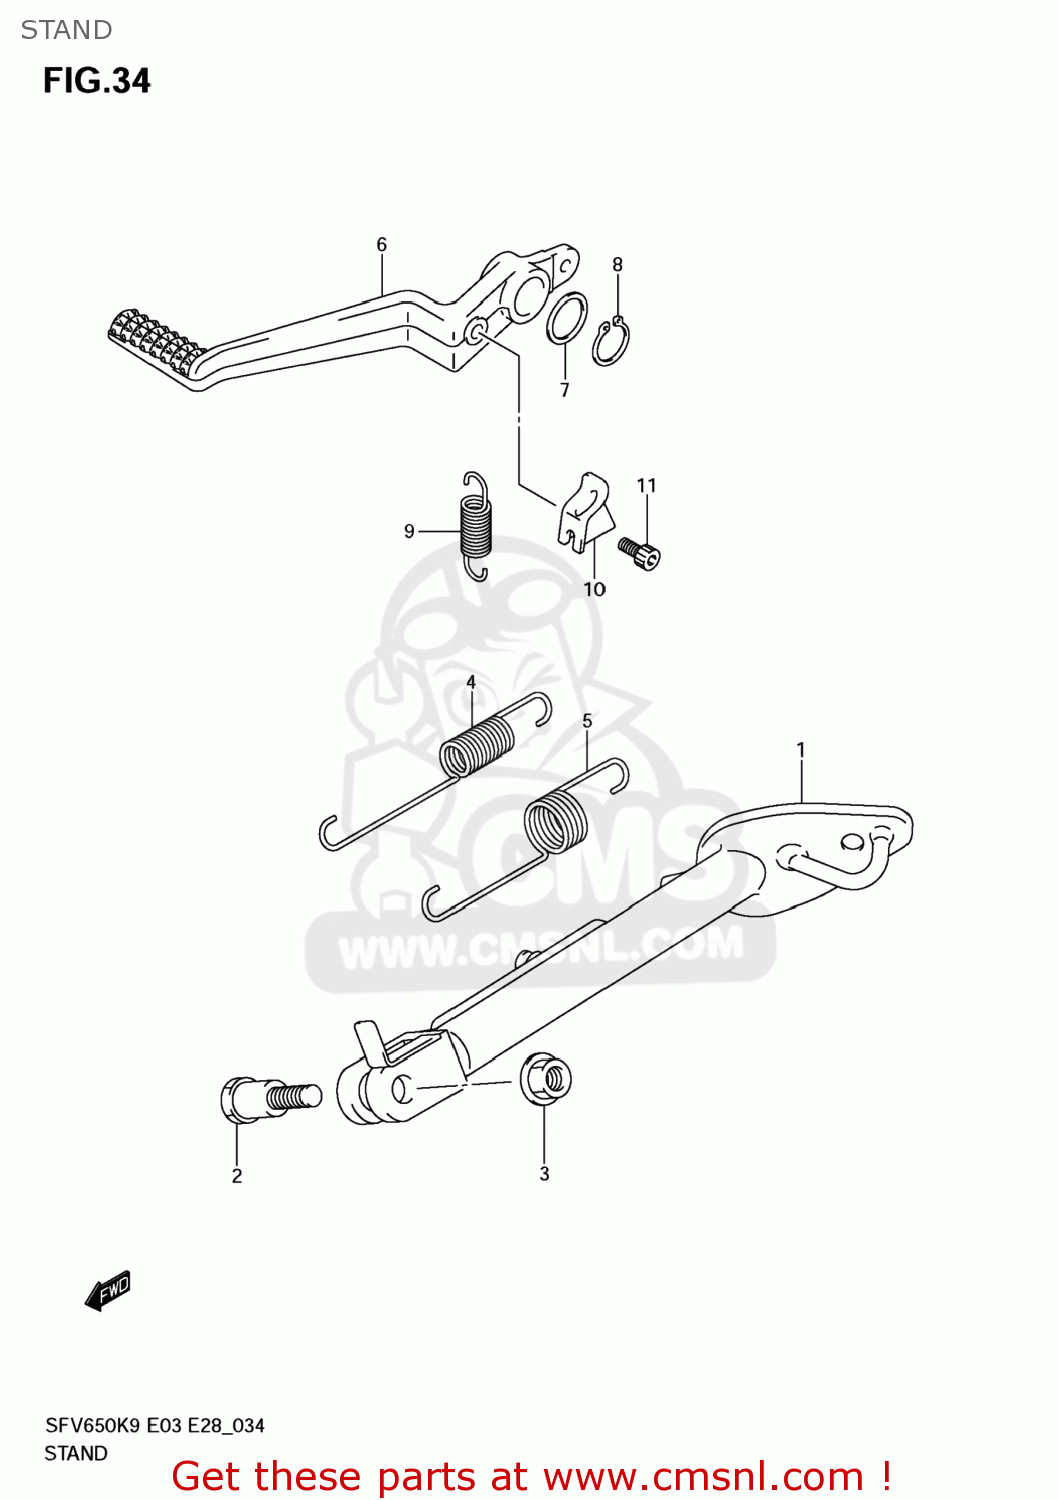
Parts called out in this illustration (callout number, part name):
1	STAND,PROP
2	BOLT(10X21)
3	NUT
4	SPRING
5	SPRING
6	PEDAL,BRAKE
7	WASHER(18X24X1)
8	CIRCLIP
9	SPRING
10	BRACKET,RETURN SPRING
11	BOLT
